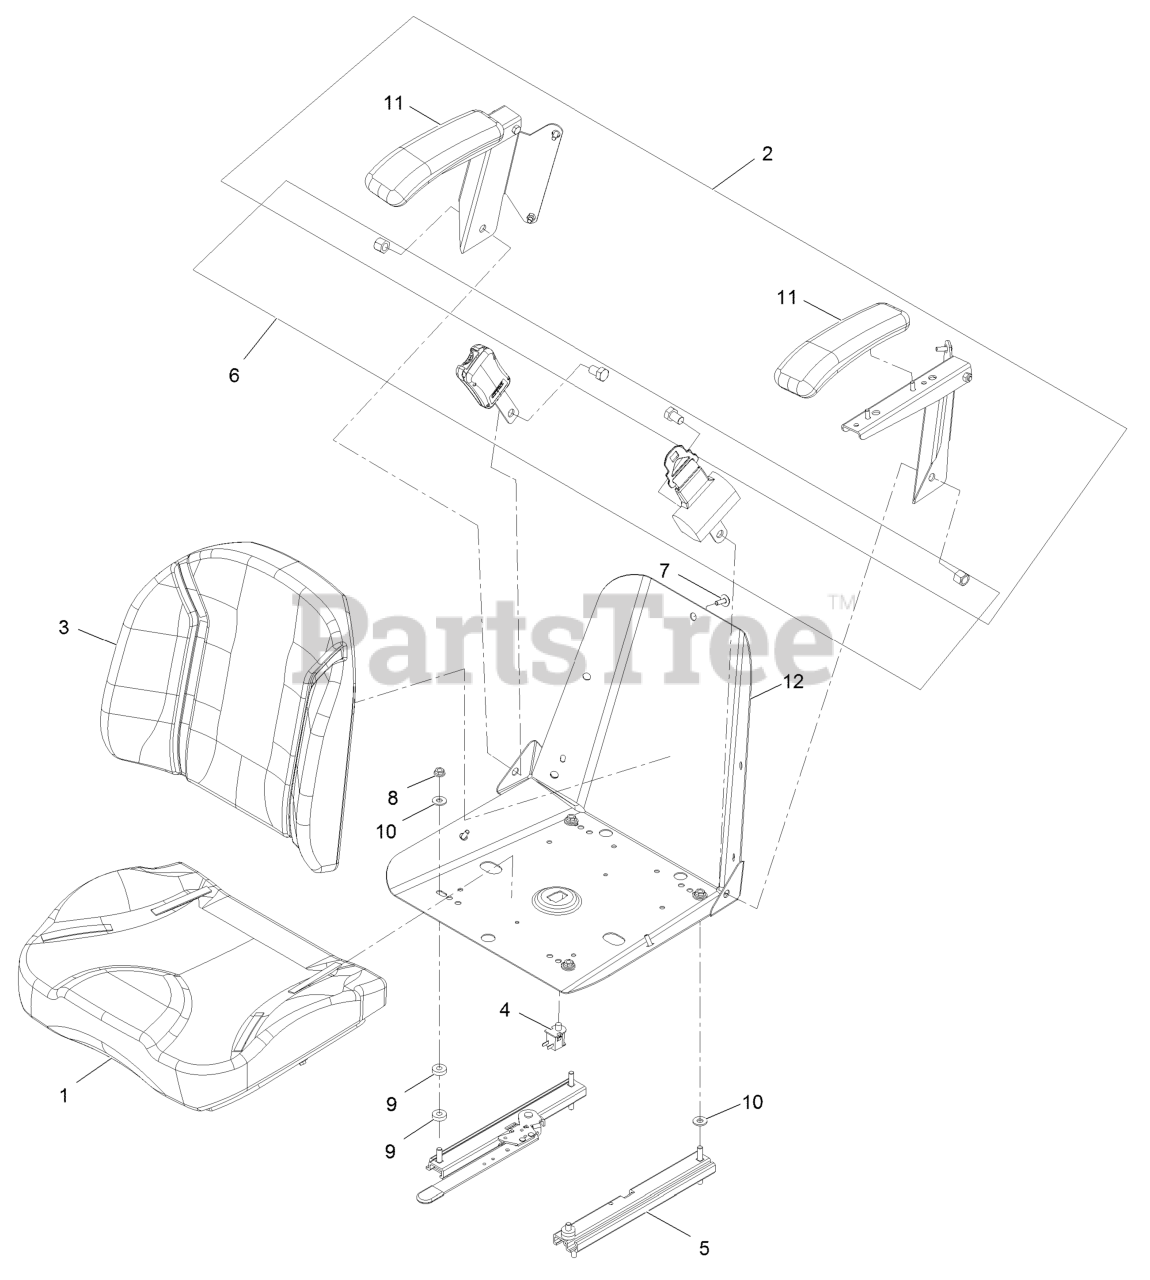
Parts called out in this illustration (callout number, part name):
1	CUSHION-SEAT BOTTOM
2	ARMREST KIT
3	CUSHION-SEAT, BACK
4	SWITCH-BAIL
5	TRACK-SEAT
6	SEAT BELT KIT
7	BOLT-SEAT
10	WASHER-FLAT
11	CUSHION-REST, ARM
12	FRAME-SEAT
